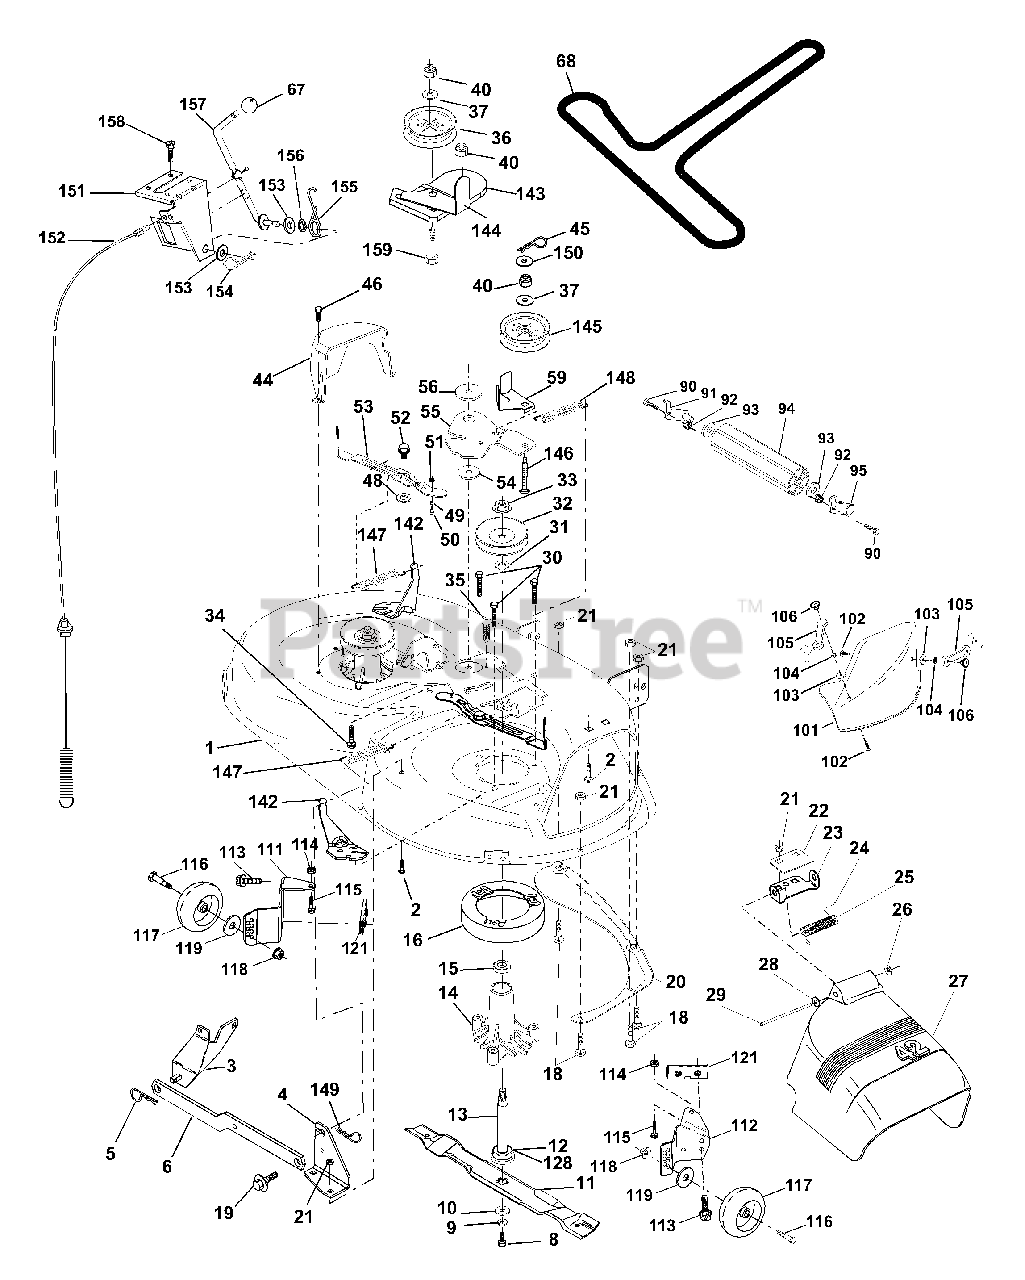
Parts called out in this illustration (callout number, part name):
1	Mower Deck Assembly, 42"
2	Bolt
3	Bracket Asm Fr. Sway Bar 3/42
4	Bracket Asm Deck 42" Sway Bar
5	Retainer Spring
6	Arm, Suspension, Rear
8	Bolt 3/8-24 x 25 Grade 8 patched
9	Washer, Lock
10	Washer,Hardened
11	Blade, Mulching 42" Std
11	Blade Mower 42" Hi-Lift Std
12	Bearing, Ball #6204
13	Shaft Assembly, Mandrel, Vented
14	Housing, Mandrel, Vented
15	Bearing, Ball, Mandrel
16	Stripper, Vented Mower Deck
18	Bolt, Carriage 5/16-18 x 5/8
19	Bolt, Shoulder
20	Baffle, Vortex
21	Nut
22	Stiffener Bracket
23	Bracket, Deflector Mower 42"
24	Cap, Sleeve 80 x 112 Blk Mower
25	Spring, Torsion, Deflector 2 52
26	Nut, Push Phos & Oil
27	Shield, Deflector 42" Blk
28	Washer 11/32 x 5/8 x 16 Gauge
29	Rod, Hinge 42" 6 75 W/G
30	Screw Thdrol Washer Head
31	Washer, Spacer Mower Vented
32	Pulley, Mandrel
33	Nut, Toplock 9/16
34	Bolt
35	Fastener, Christmas Tree
36	Pulley, Idler, Flat
37	Washer 13/32 x 13/16 x 16 Gauge
40	Nut
44	Guard, Mandrel, LH
45	Retainer
46	Screw, Thdrol 1/4-20 x 5/8 T
48	Washer,Hardened
49	Roller Assembly, Cam Follower
50	Bolt, Shoulder #10-24 Grade 5
51	Locknut
52	Bolt, Shoulder 5/16-18 UNC
53	Arm Assembly, Pad, Brake
54	Washer,Hardened
55	Arm, Idler
56	Spacer, Retainer
59	Guard TUV Idler
67	Knob Round
68	V-Belt, 42" Mower
90	Bolt Fin Hex 3/8-16 Unc x 1
91	Bracket Asm Noseroller LH
92	Nut, Lock, Hex W/Ins 3/8-16 UNC
93	Washer 17/3 x 7/8 x 6 Ga.
94	Roller Nose 38 & 42
95	Bracket Asm Noseroller RH
101	Mulcher Cover
102	Screw
103	Washer, Flat
104	Washer, Lock
105	Latch Assembly
106	Nut, Weld
111	Bracket, Gauge, Wheel LH
112	Bracket, Gauge, Wheel RH
113	Screw 5/16 - 18 x 3/4
114	Nut, Keps 5/16 - 18 UNC
115	Bolt, Carriage 5/16-18 x 1/2
116	Bolt, Shoulder
117	Wheel, Gauge
118	Nut Centerlock 3/8-16
119	Washer 3/8 x 7/8 x 14 Ga.
121	Bracket, Extruded
128	Washer, Felt
142	Arm Spring Brake Mower
143	Bracket Arm Idler 42"
144	Keeper Belt 42" Clutch Cable
145	Pulley Idler Flat
146	Bolt Carriage Idler
147	Spring Extension
148	Spring Return Idler
149	Retainer Spring Yellow
150	Washer 9/32 x 3/4 x 16 Ga.
151	Bracket Clutch Cable
152	Clutch Cable 42"
153	Washer Flat 3/8" Type B
154	Spring Retainer
155	Spring Retention LVR CLTCH CAB
156	Spacer Clutch Cable
157	Rod Clutch Cable 3/8"
158	Screw Hex Thd Cut 1/4-20 x 5/8
159	Bolt Rdhd Sqn 3/8-16 UNC x 1-3/4
